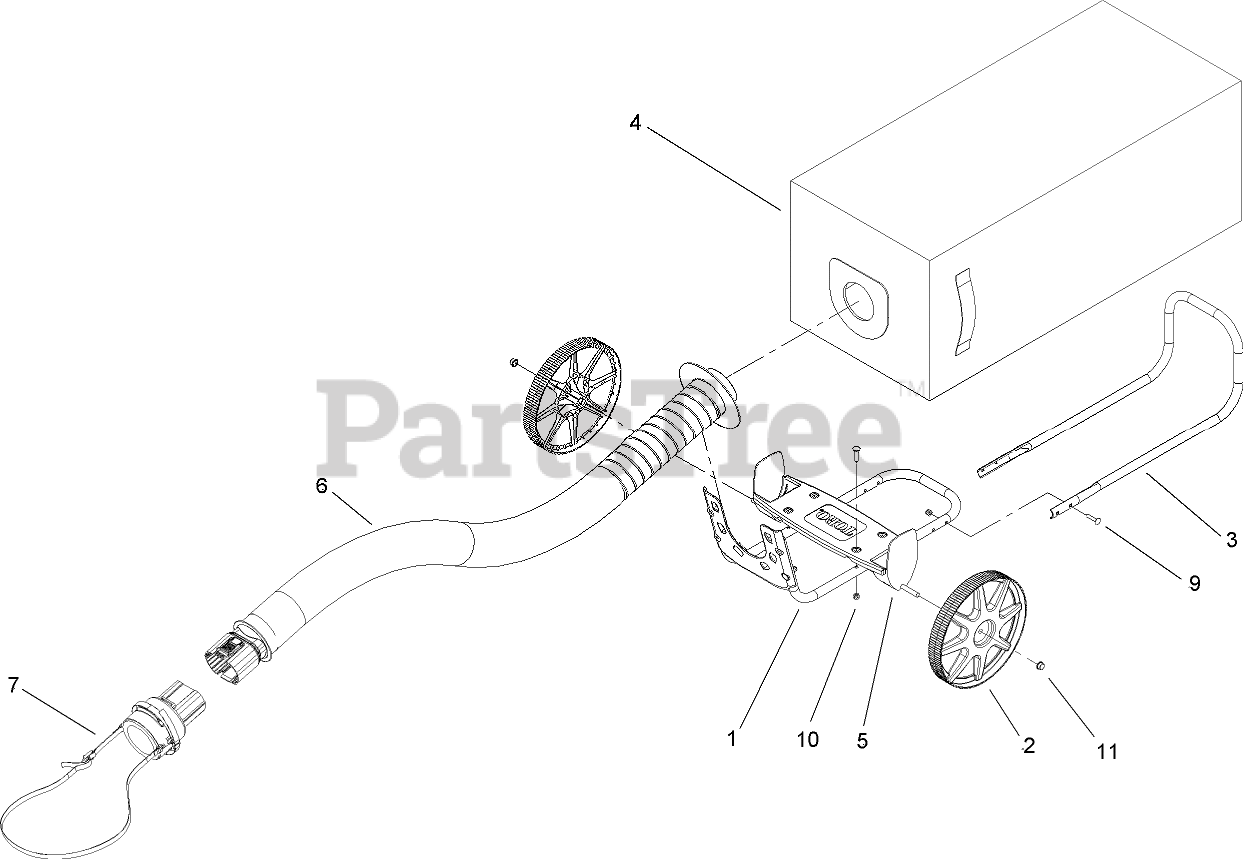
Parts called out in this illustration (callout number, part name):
1	TUBE-FRONT
2	WHEEL-10 INCH
3	TUBE-REAR
4	BAG ASM
5	FENDER ASM
6	HOSE ASM
7	COUPLER-UNIVERSAL
9	SCREW-CARRIAGE
10	NUT-LOCK, NI
11	NUT-PUSH
